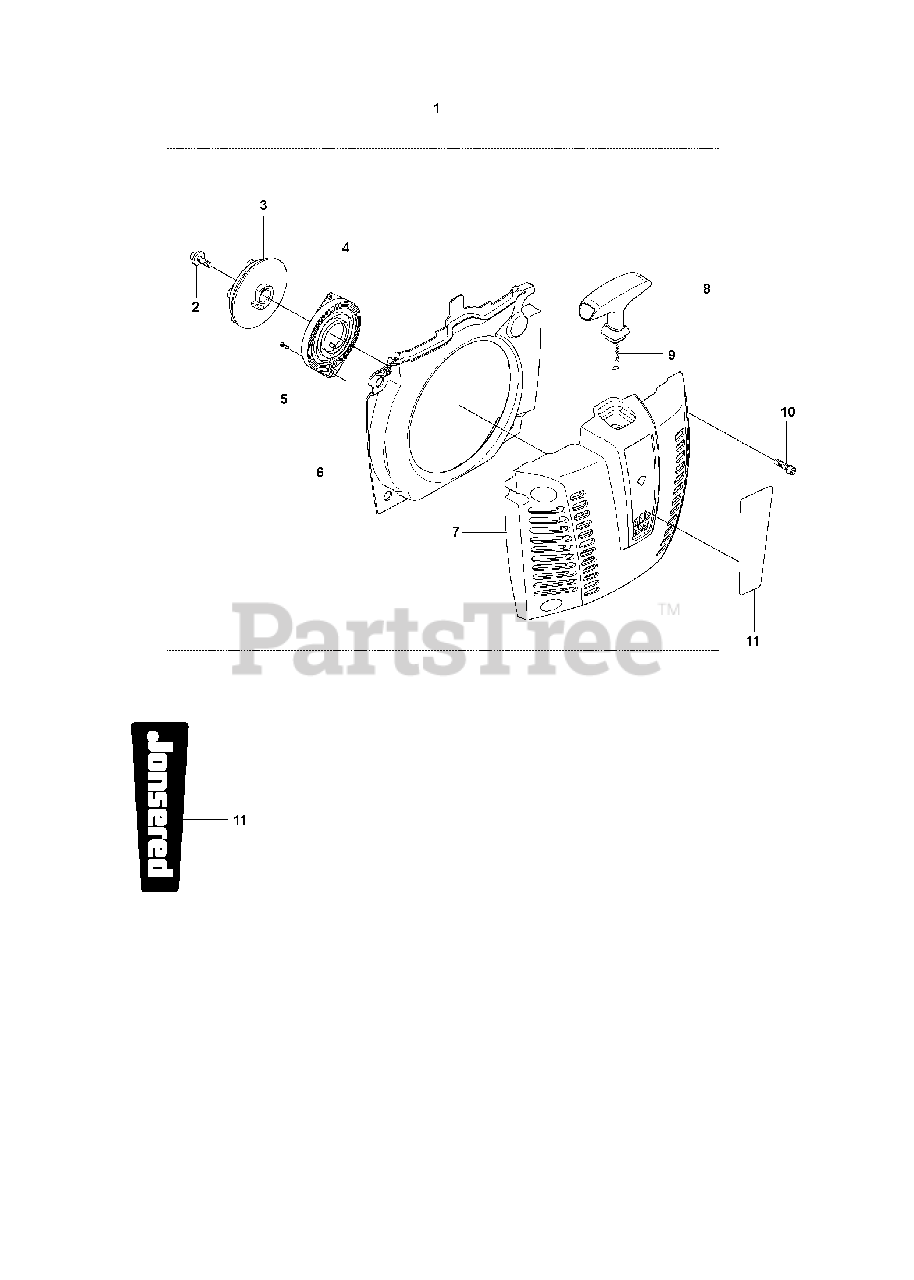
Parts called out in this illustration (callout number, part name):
2	SCREW
3	STARTER PULLEY
4	RECOIL SPRING
5	SCREW
6	AIR CONDUCTOR
7	STARTER HOUSING
8	STARTER HANDLE
9	STARTER ROPE
10	SCREW IHSCFM
11	STARTER HOUSING DECAL
